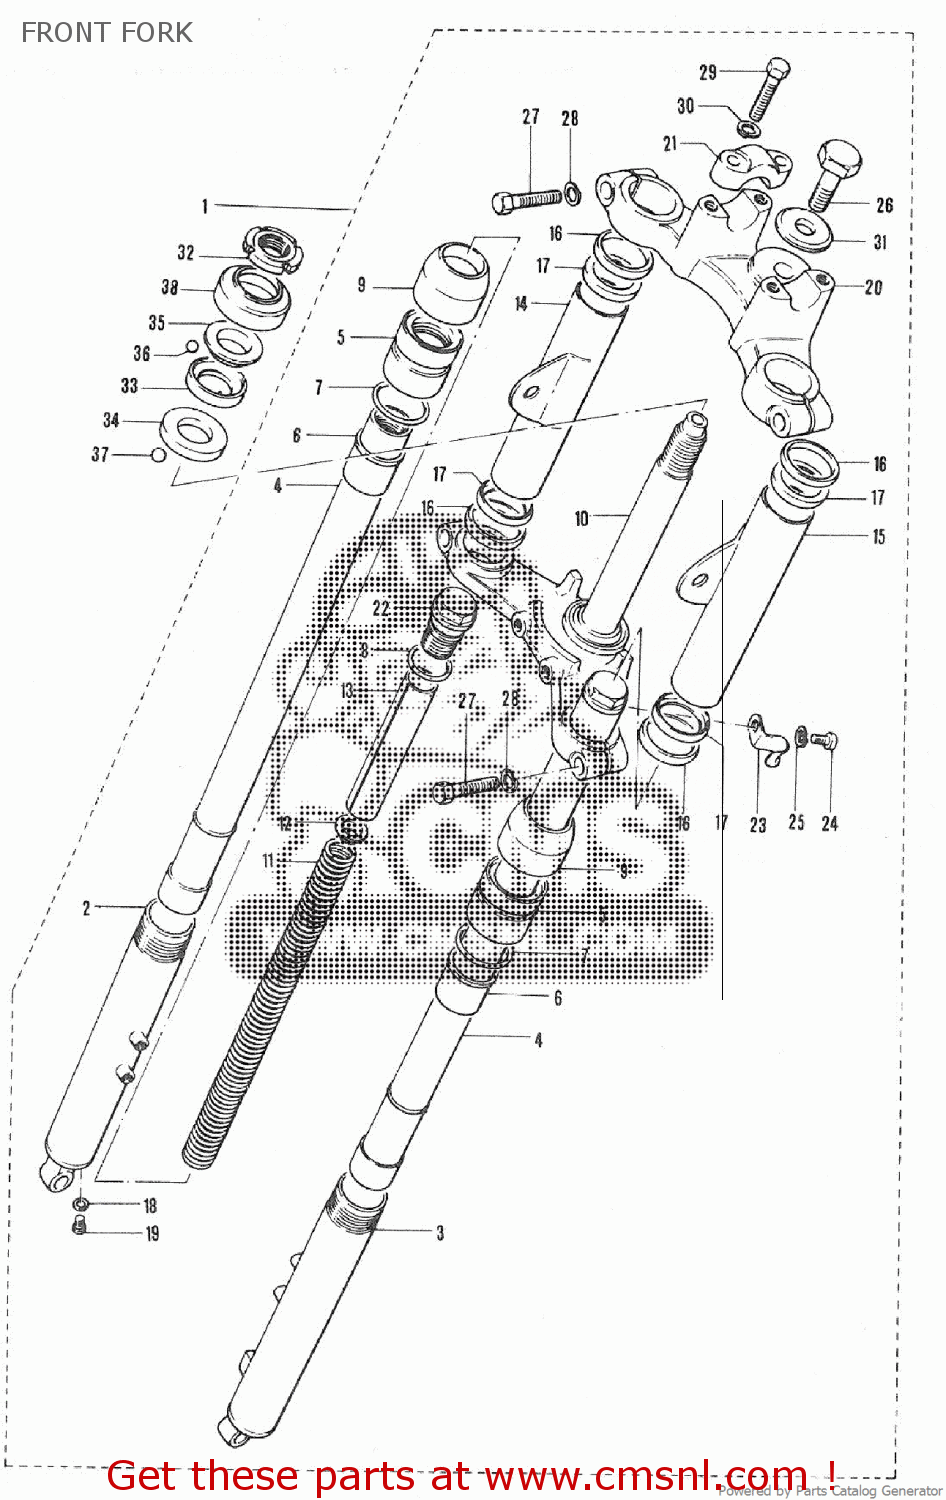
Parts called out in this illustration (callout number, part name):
1	DAMPER SET
2	TUBE,OUTER,RIGHT
3	TUBE,OUTER,LEFT
4	TUBE,FORK,INNER
5	NUT,FORK OUTER TUBE
6	BUSHING,GUIDE
7	O RING,OIL SEAL LWR
8	O-RING,FORK INNER TUBE
9	SEAL,DUST
10	STEM,STEERING
11	SPRING
12	GUIDE,FRONT FORK SPRING C
13	SPACER,SPRING
14	BRACKET COMP,HEADLAMP
15	BRACKET,HEADLAMP,LEFT
16	CUSHION,HEADLAMP BRACKET
17	SEAT,HEADLAMP BRACKET
18	GASKET,DRAIN,PLUG (NAS)
19	CROSS HEAD SCREW
20	STEERING STEM HEAD
21	HOLDER,HANDLEBAR
22	CAP,FRONT FORK
23	CLIP,BRAKE CABLE
24	SCREW, CENTER SHAFT
25	LOCK WASHER
26	BOLT,FORK INNER TUBE
27	BOLT,FORK INNER TUBE F
28	LOCK WASHER
29	BOLT
30	LOCK WASHER
31	WASHER,STEERING STEM
32	NUT,STEERING
33	RACE,STEERING,INNER,UPPER
34	RACE,STEERING,INNER,UPPER
35	LACE,STEERING OUTER UPR
36	BALL
37	STEEL BALL
38	COVER,STEERING,UPPER
